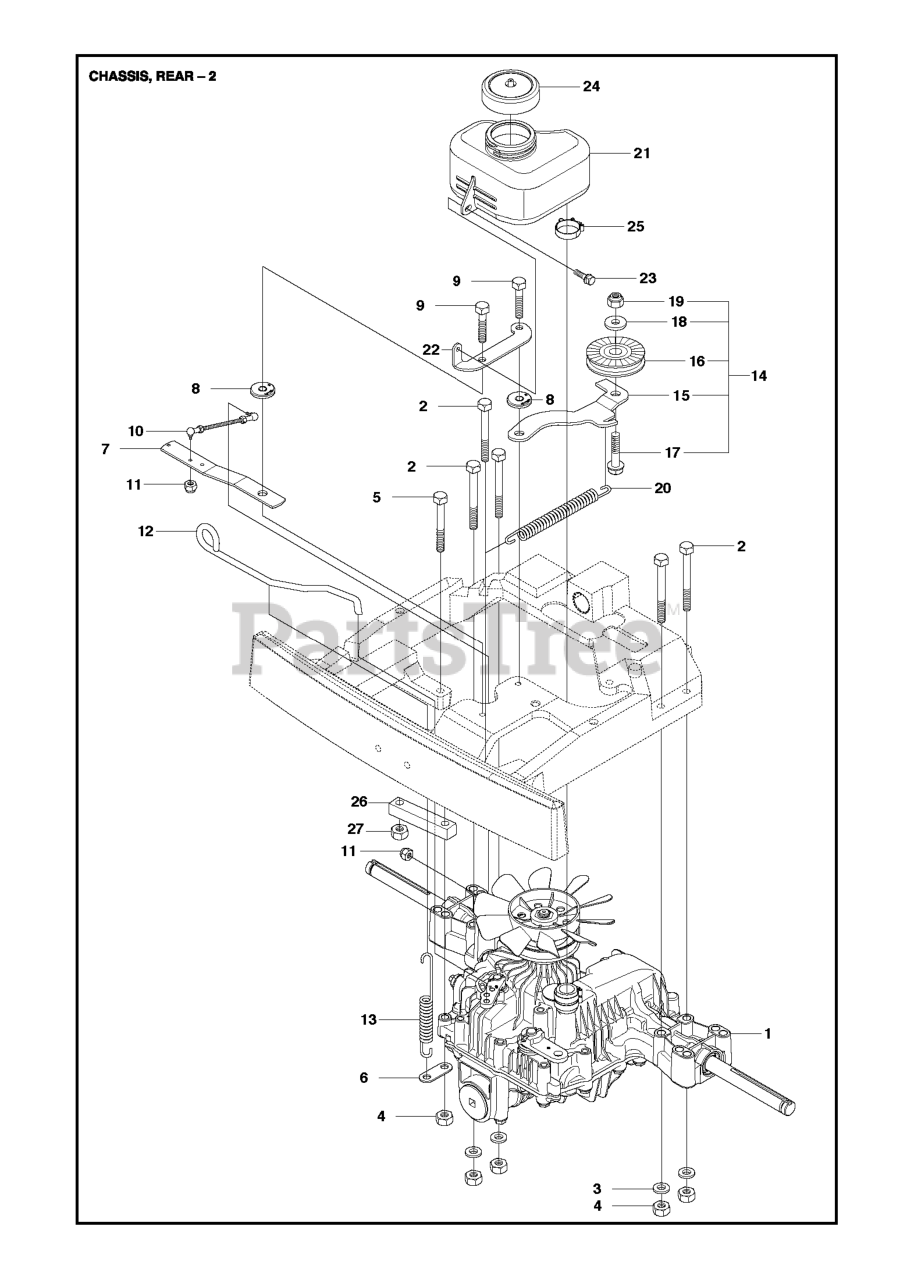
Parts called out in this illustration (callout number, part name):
1	TRANSMISSION K574A
2	SCREW
2	Hex Bolt
3	WASHER BRB 8.4X17
4	NUT
11	LOCKNUT M5
15	BELT TENSIONER ARM
17	SCREW
19	LOCKNUT M8
25	HOSE CLAMP 20-32
26	BRACKET
27	NUT
